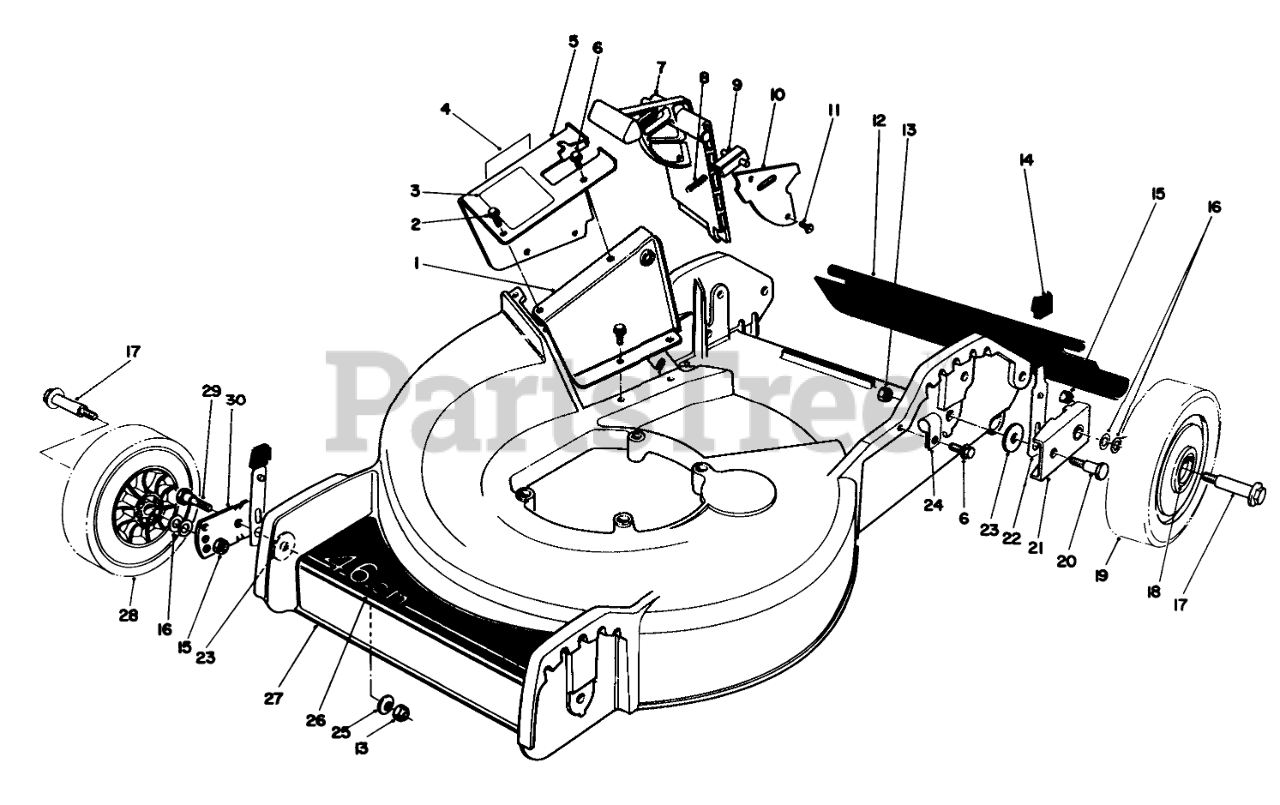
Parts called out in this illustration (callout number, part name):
1	Tunnel-Inner
2	SCREW
3	DECAL - DANGER
4	DECAL-DANGER
5	Tunnel-Outer (Incl. Ref. #3 & 4)
6	SCREW
7	Door-Mulching
8	SPRING-COMPRESSION, LATCH
9	Door Latch
10	DOOR COVER
12	SHIELD - TRAILING
13	NUT-LOCK, NI
14	KNOB-ARM
15	Nut
16	WASHER
17	BOLT-WHEEL
18	BUSHING
19	Wheel & Tire Assembly (Incl. Ref. #18)
20	PIVOT SCREW
21	PIVOT ARM ASM
22	SPRING ARM ASM
23	PIVOT WASHER
24	CLAMP-R
25	WASHER-BELLEVILLE
26	Decal-Deck
27	HSG & CARTON
28	Wheel & Tire Assembly (Incl. Ref. #18)
29	PIVOT SCREW
30	PIVOT ARM ASSY
